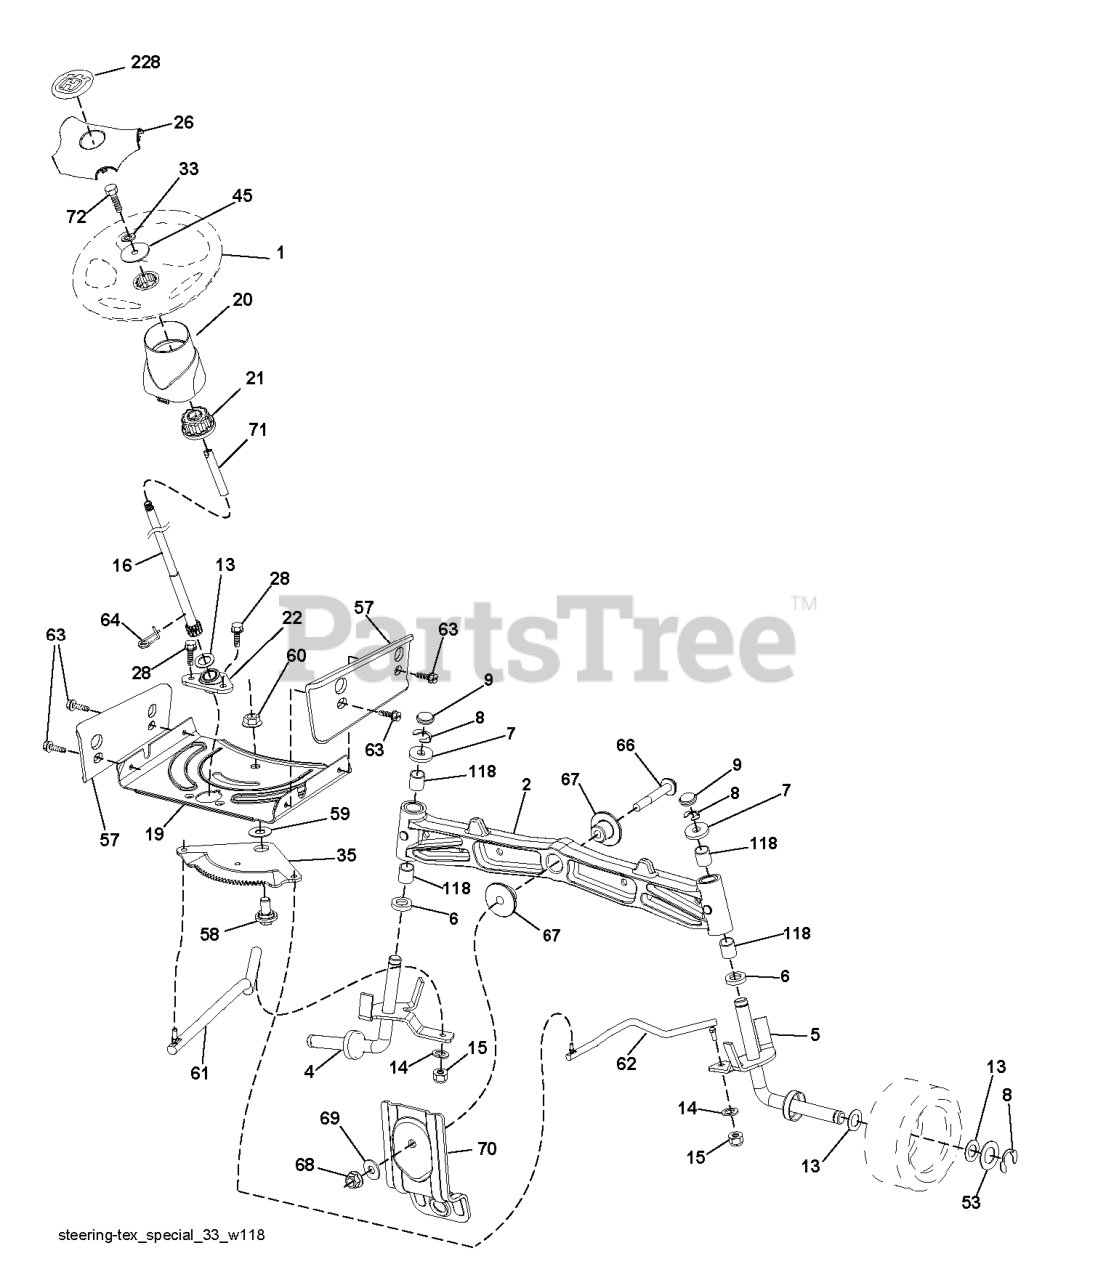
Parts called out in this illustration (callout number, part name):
1	RP WHEEL.STEER.HUSQ.PREM.OVMLD
2	AXLE.SVC.ASM CAST IRON.TEX
4	SPINDLE.WELDED.LH.15"TEX
5	SPINDLE.WELDED.RH.15"T
6	THRUST WASHER
9	CAP.SPINDLE.BLACK
14	WASHER, LOCK 3/8
15	NUT CROWNLOCK 3/8-24
16	SHAFT STEERING
19	PLATE.STEER.DDL.NLT/NG
20	BOOT, STEERING
21	ADAPTER, WHEEL STNG..
22	BUSHING.ASM.STEERING.A
26	RP INSERT.CAP.WHL.STRG.HUSQ.
28	SCREW, 3/8-16X3/4
33	WASHER.LOCK.HVY.HLCL.SPR.5/16
35	GEAR.SECTOR.PLATE.DDL.
45	WASHER.11/32
53	WASHER.HARDENED
57	BRACKET.UPSTOP.TEX
58	BOLT.SHOULDER.SECTOR.P
59	WASHER.THURST.SECTOR.S
60	NUT FLANGE LOCK 5/8-11
61	DRAGLINK.LH.BALLSTUD.D
62	DRAGLINK.RH.BALLSTUD.D
63	SCREW
64	RETAINER.CLIP.SPRING.S
66	BOLT HEX FGHD 7/16-14 X 3 SERR
67	BUSHING.PM.FRONT AXLE
68	NUT.LOCK.FLANGE.7/16
69	WASHER.1.5X.505X.118
70	BRKT.DECK.SUSPENSION.F
71	SHAFT EXTENSION STEERING
72	BOLT YT
118	BUSHING, AXLE CAST
228	DECAL.WHEEL.STRG.LGN.H
